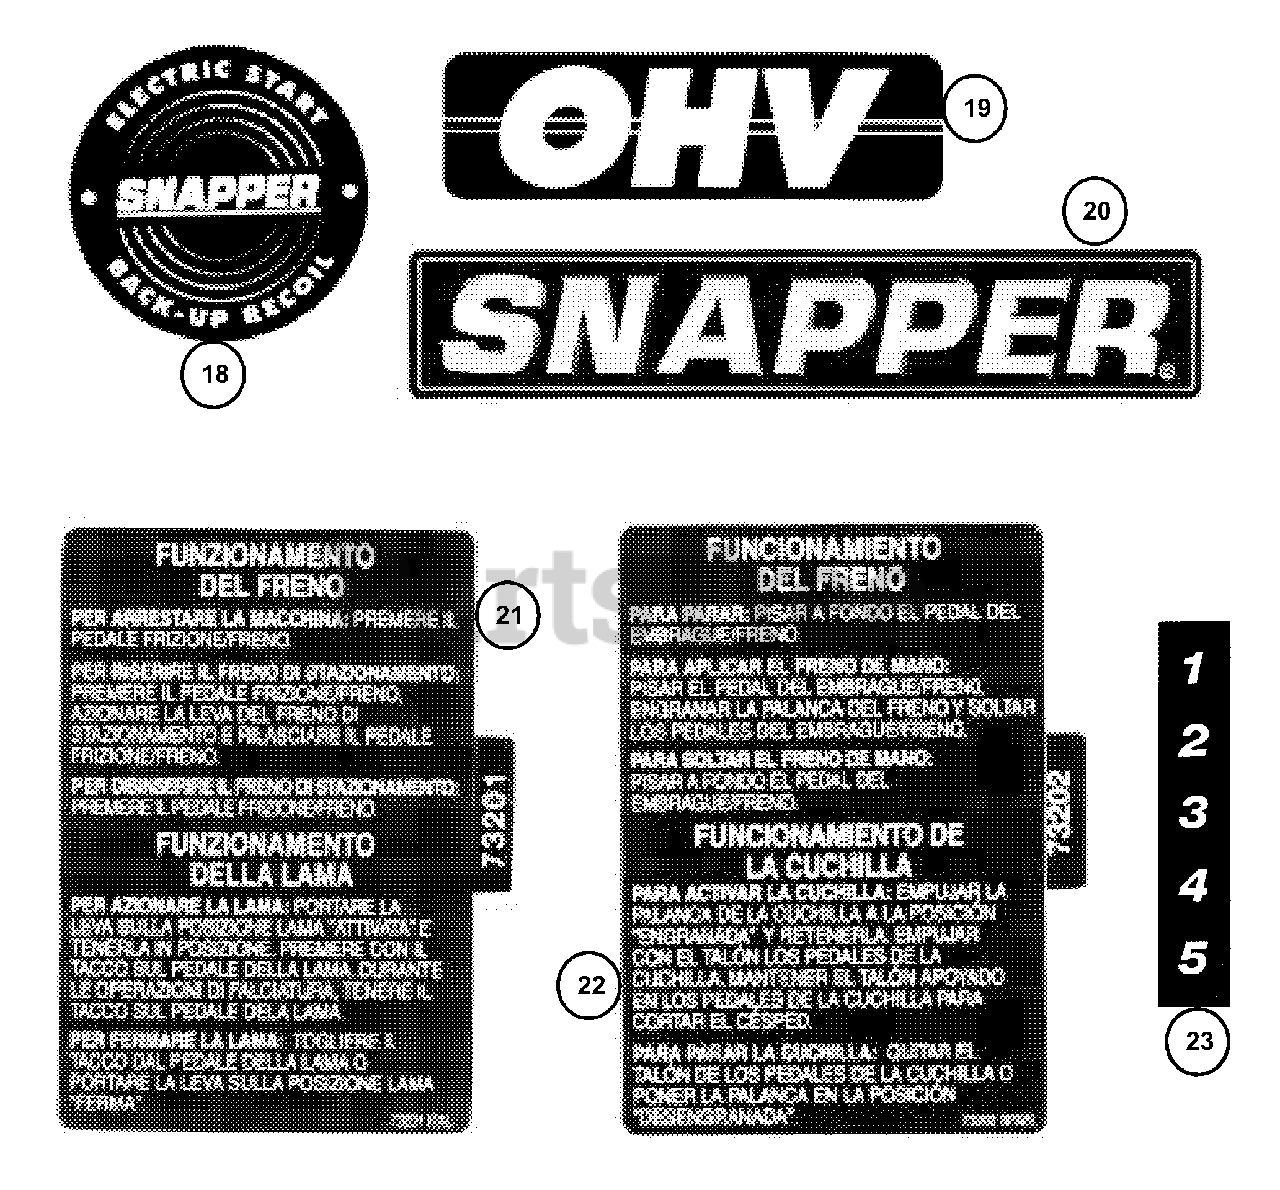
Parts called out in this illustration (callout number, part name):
18	DECAL, Back-Up Recoil
19	DECAL, OHV
20	DECAL, Snapper
21	DECAL, Brake Operation (Italian)
22	DECAL, Brake Operation (Spanish)
23	DECAL, Height of Cut
